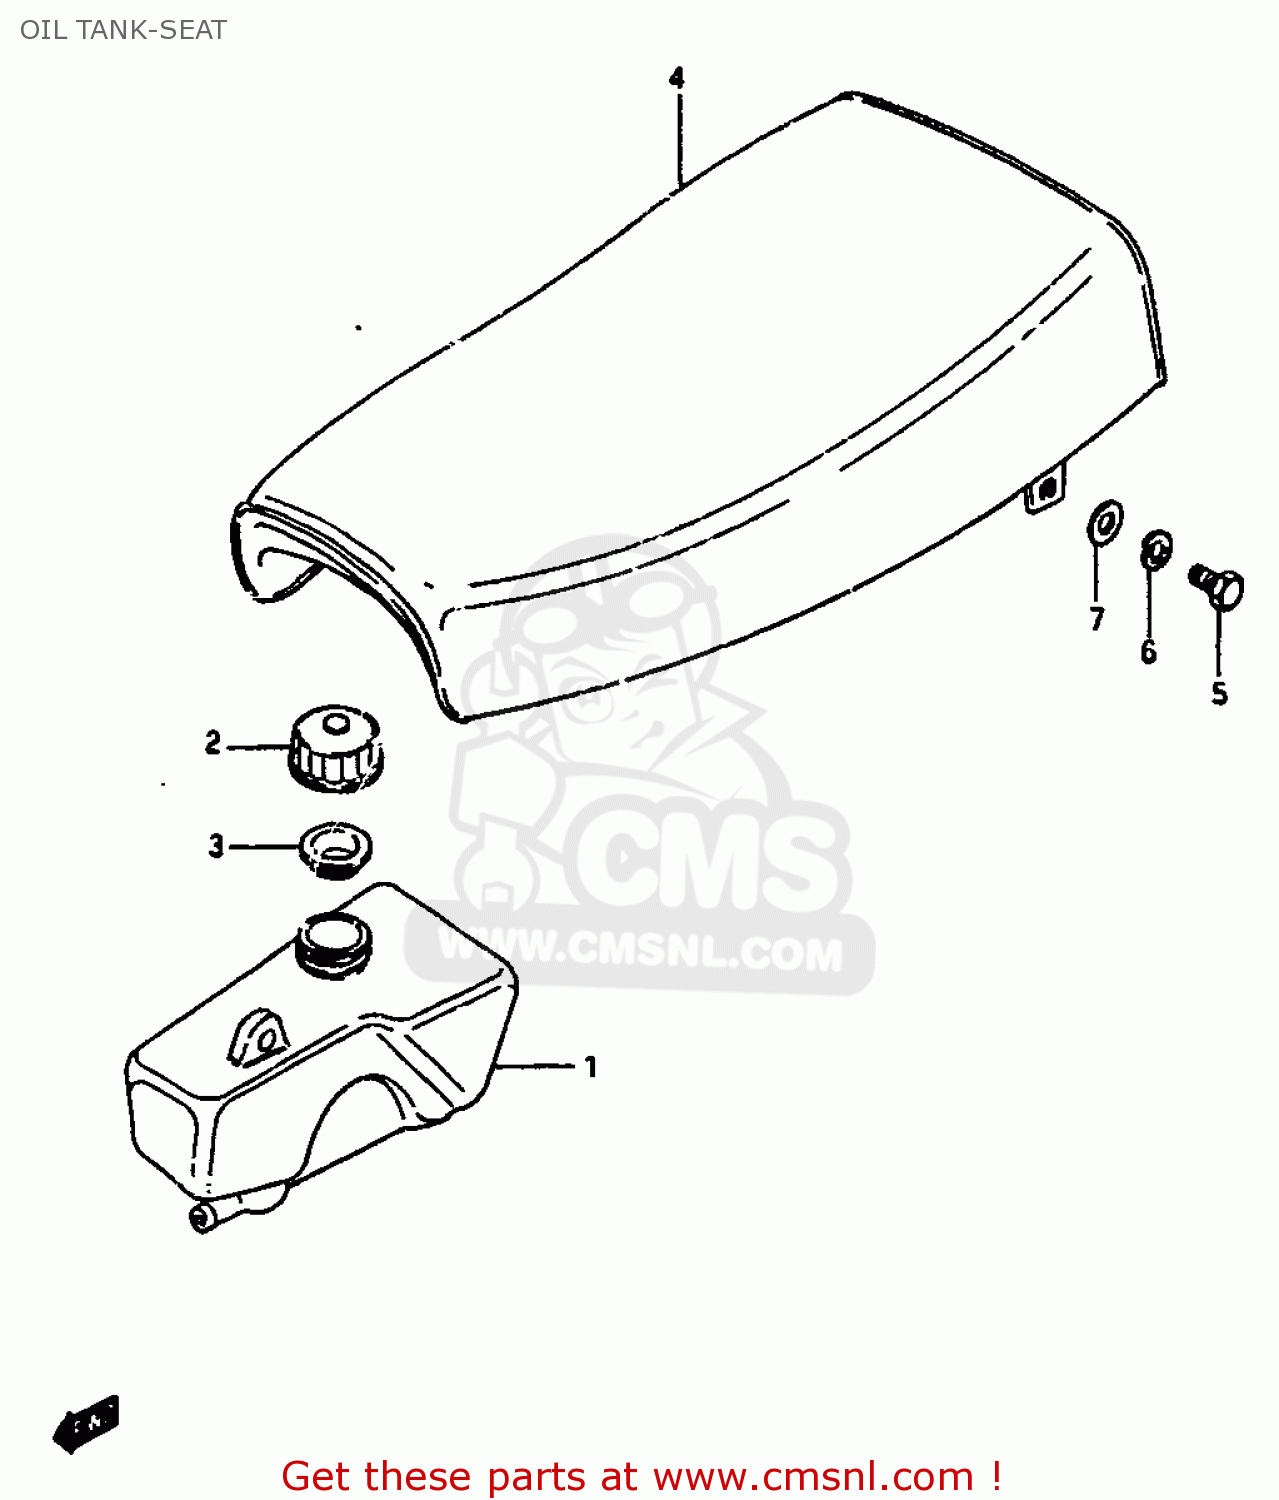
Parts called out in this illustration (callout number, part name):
1	TANK,OIL
2	CAP,OIL TANK FILLER
3	GASKET,OIL TANK (NAS)
4	SEAT ASSEMBLY
5	BOLT
6	WASHER,LOCK
7	WASHER
